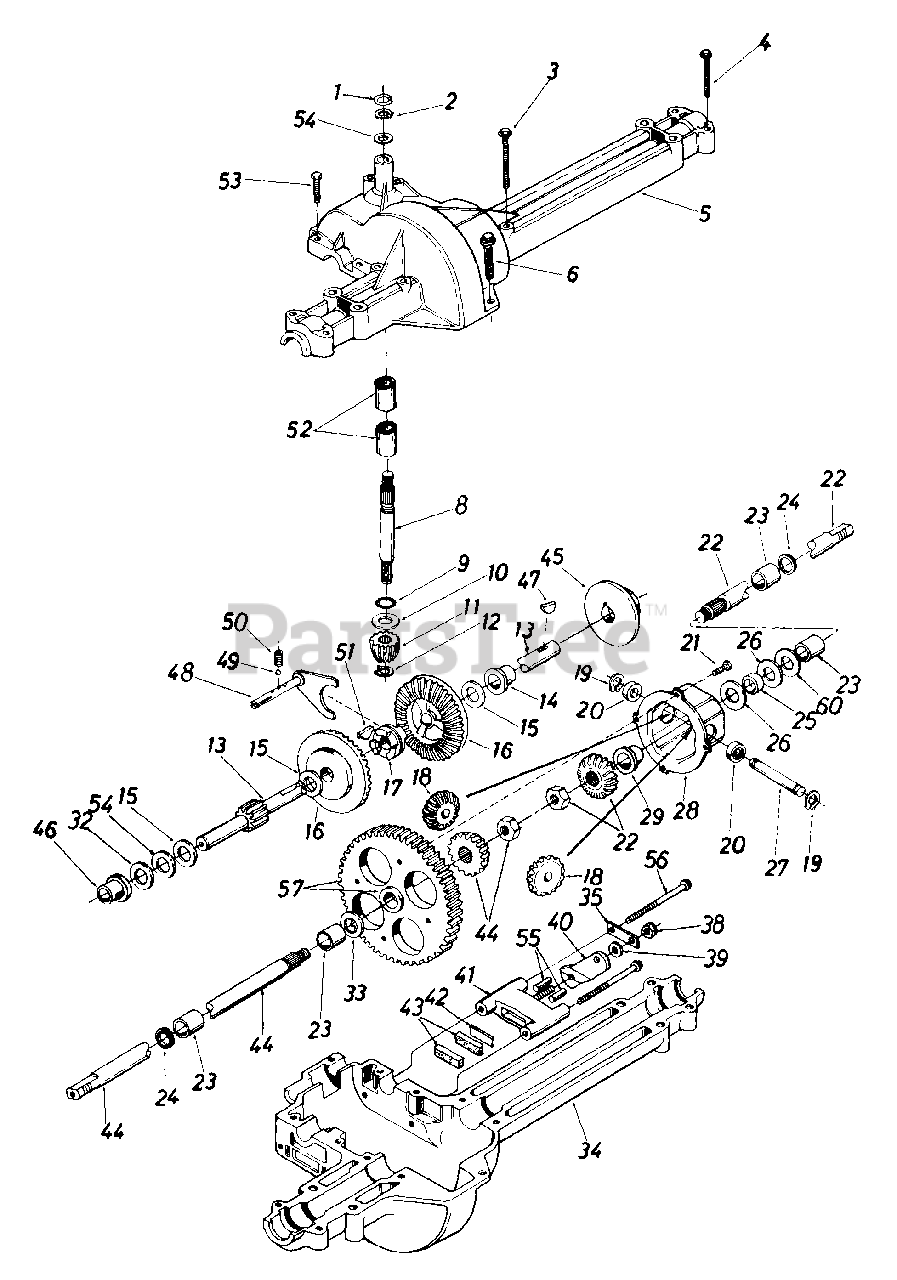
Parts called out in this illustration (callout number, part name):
1	Wire Ring
2	Retaining - Ring
3	Hex Bolt 1/4-20 x 1.75" Lg.
4	Hex Tap Scr. 1/4-20 x 1.25" Lg.
5	Upper Housing
6	Hex TT-Tap Scr. 1/4-20 x .75" Lg.
8	Input Shaft
9	Square Seal 5/8" I.D.
10	Thrust Washer 5/8" I.D. x 1.25" O.D.
11	Pinion Input 14T
12	Retaining Ring
13	Drive Shaft
14	Flange Brg. 5/8" I.D. x 3/4" Lg.
15	Fl-Wash. 5/8" I.D. x 1.25"
16	Bevel Gear 42T
17	Clutch Collar
18	Miter Gear 157 (H.D.)
19	Snap Ring
20	Thrust Bearing
21	Pan Head Scr. 1/4-20 x .50" Lg. w/Patch
22	Axle R.H. Ass'y.
23	Sleeve Bearing 3/4" I.D. x 1.0" Lg.
24	Oil Seal 3/4" I.D.
25	Axle Spacer
26	Fl-Wash..760" I.D. x 1.5" O.D.
27	Cross Shaft
28	Differential Can Ass'y.
32	Thrust Wash. 5/8" I.D. x 1" O.D. x .025" Thk.
33	Fl-Wash..760" I.D. x 1.5" O.D.
34	Lower Housing
35	Anti-Rotation Brkt.
38	Hex Nut 5/16-24 Thd.
39	Fl-Wash..344" I.D. x .875" O.D.
40	Actuating Arm
41	Brake Yoke
42	Puck Plate
43	Brake Puck
44	Axle L.H. Ass'y.
45	Brake Disc
46	Flange Bearing 5/8" I.D. x 15/16" Lg.
47	Woodruff Key 3/16 x 5/8 HT
48	Shift Fork Ass'y.
49	Ball Detent .250" Dia.
50	Spring Detent
51	#9 Hi-Pro Key 3/16" x 3/4" Dia. HT
52	Needle Brg. 5/8" I.D. x 1/2"
53	Hex Bolt 1/4-20 x 1.00" Lg.
54	Fl-Wash. 5/8" I.D. x 1" O.D. x .020 Thk.
55	Actuating Pin 5/16" Dia.
56	Hex Wash Hd. Self-Tap Scr. 1/4-20 Thd.
57	Differential Gear 727 Ass'y. w/Bearing
60	Fl-Wash..76" I.D. x 1.5" O.D. x .010" Thk.
